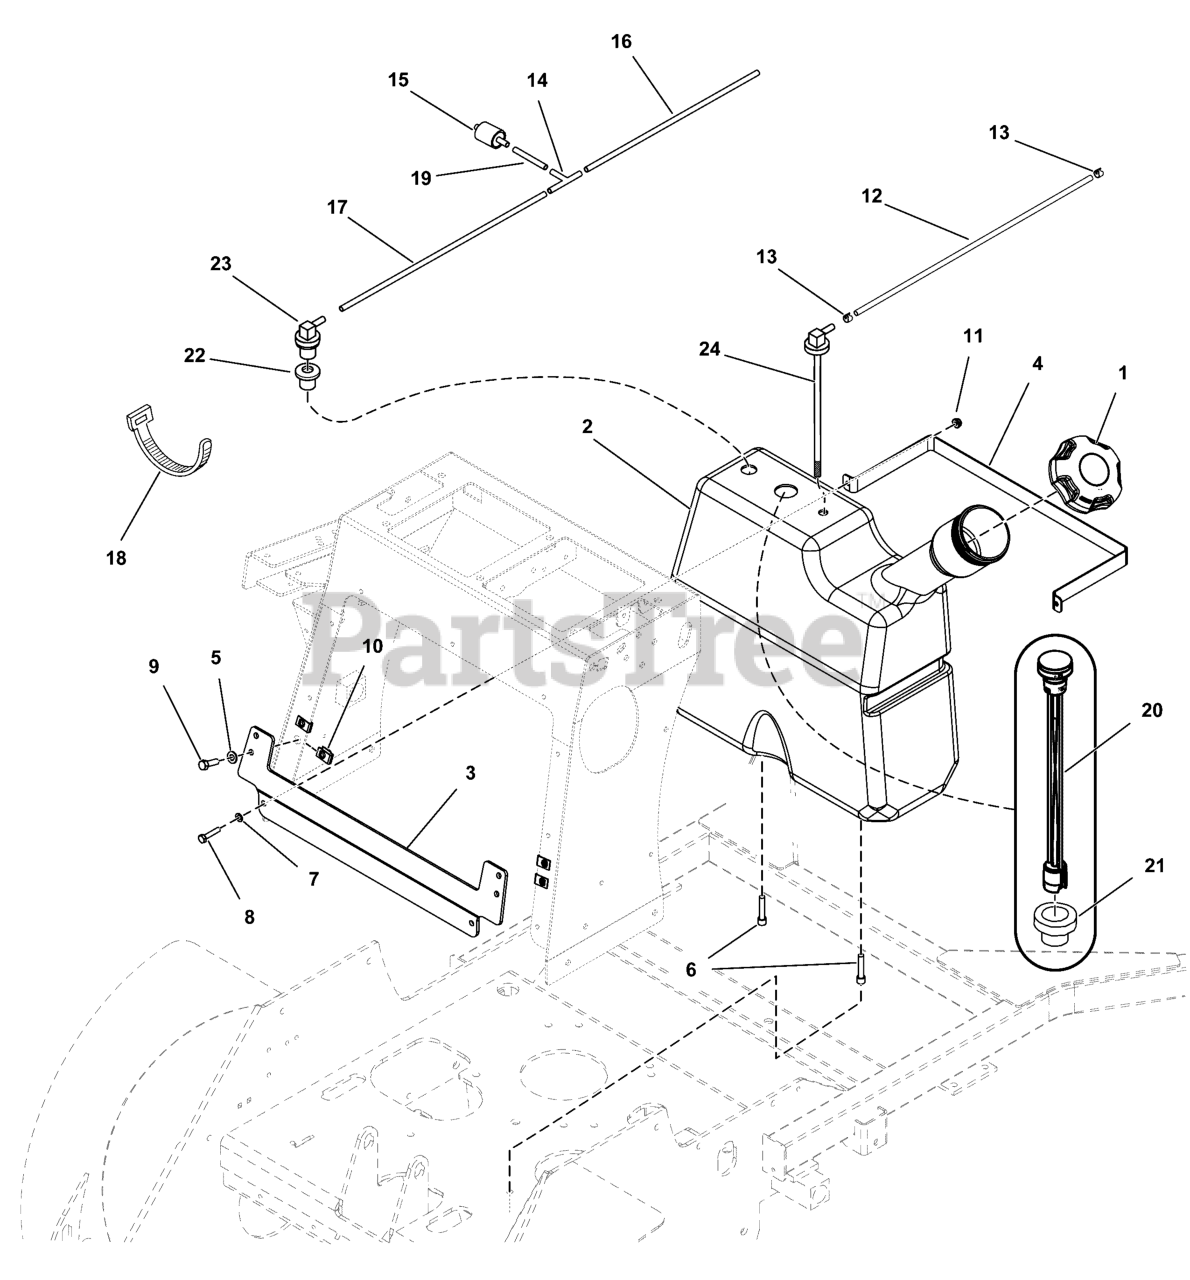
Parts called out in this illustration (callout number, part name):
1	FUEL CAP, 3.25", MANAGED VENT, 16"TETHER
2	TANK, FUEL, STAND -ON, 7.75 GALLON
3	PLATE, SRS Z2 TANK MOUNT, 7.75GAL - BLK
4	STRAP, FUEL TANK, STAND ON - BLK
5	WASHER, 5/16" SAE
6	SCREW, SOC HD, 5/16-18 X 1/2
7	WASHER, 1/4 SAE
8	BOLT, 1/4-20 X 1" GD5 CZ
9	BOLT, 5/16-18 X 1" GRD5 YZ
10	BODY CLIP, 5/16-18-7GA MATERIAL
11	NUT, 1/4-20 Hex Nylock Flange
12	1/4" Fuel Line, 7" Long
13	CLAMP, Hose
14	FITTING, 3/16" TEE, BARB TYPE, HDPE
15	FILTER, FUEL
16	HOSE, VAPOR, 5MM ID, 15.00 LG
17	HOSE, VAPOR, 5MM ID, 19.00 LG
18	TIE, SELF-LOCKING, 6"
19	HOSE, VAPOR, 5MM ID, 2.00 LG
20	GAUGE, FUEL LEVEL, 17.0"
21	GROMMET, FUEL GAUGE
22	GROMMET (SV)
23	REMOTE VENT ASSEMBLY
24	PICKUP TUBE ASM, FUEL TANK, 16.50"
